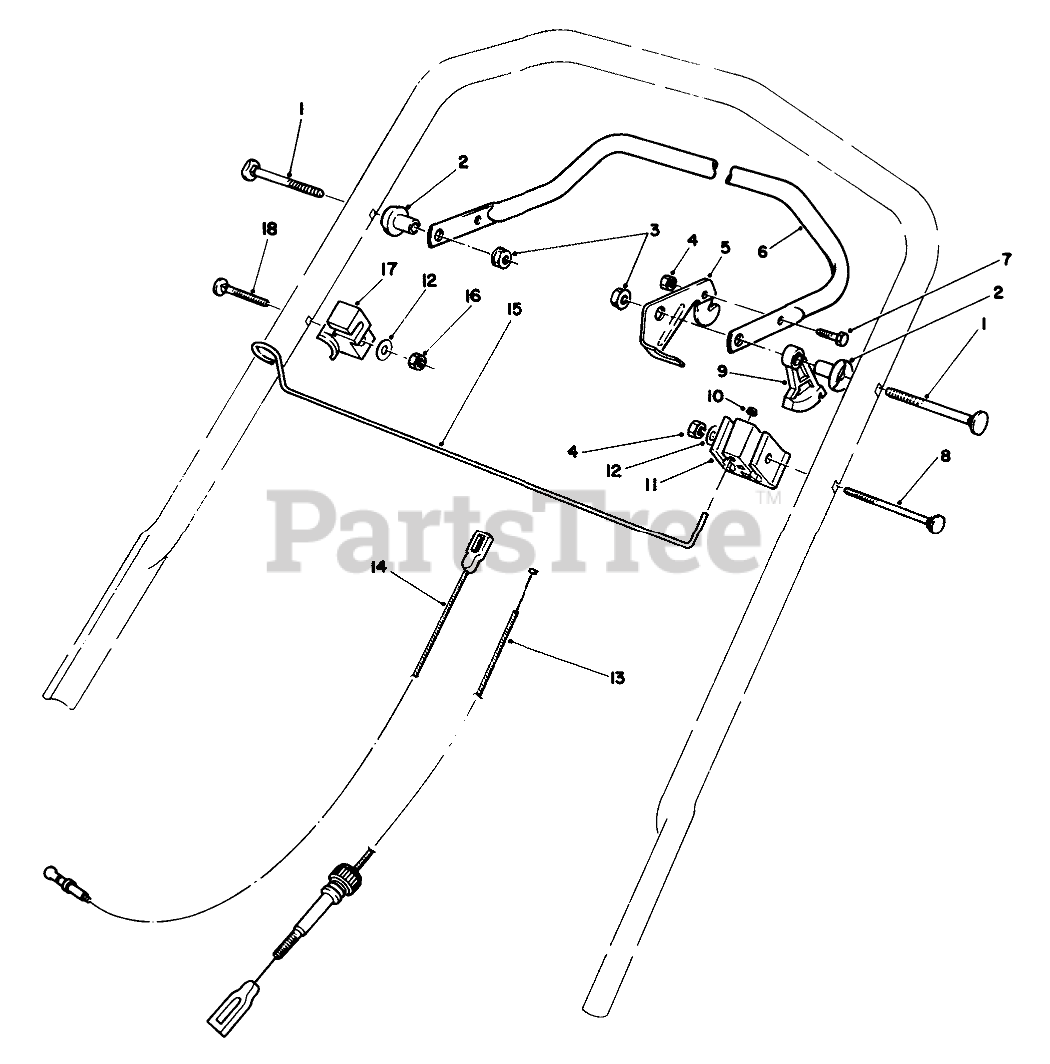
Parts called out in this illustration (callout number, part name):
1	5/16-18 X 2 HNDLE SCREW
2	SPACER-SUPPORT
3	NUT-LOCK, NI
4	NUT-LOCK, NI
5	LEVER-CONTROL
6	Bar-Control
7	SCREW-HH
8	HANDLE SCREW
9	LEVER-TRACTION
10	NUT-SPEED
11	SUPPORT-CABLE
12	WASHER-FLAT
13	CABLE-TRACTION
14	BRAKE CABLE
15	ROPE ROD PLATED
16	NUT-HEX
17	ROD CATCH
18	SCREW-HANDLE
